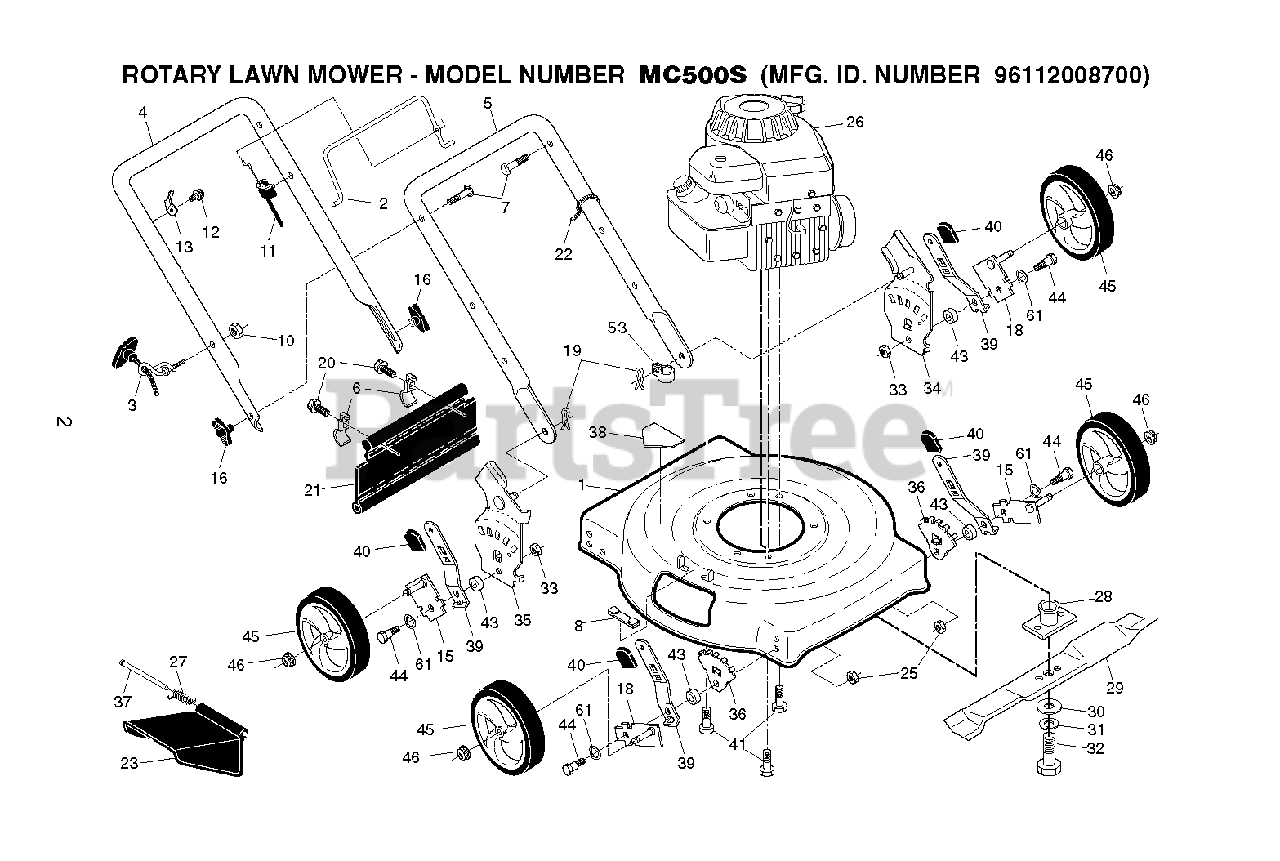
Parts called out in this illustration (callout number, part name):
1	HOUSING.22.ECON.PUSH.BLACK.WAL
2	BAIL.CONT.D.STRAIGHT.PUSH.BLK
3	GUIDE.ROPE.STD.BLK.ZIN
4	HANDLE.UPPER.ECONOMY.BLACK
5	HANDLE.LOWER.D-STRAIT.BLACK
6	BRACKET.SKIRT.BZP
7	BOLT, HANDLE 5/16-18X1.75
8	CLIP. CLOSEOUT
10	NUT
11	CABLE.MZR.RATO.22"LOW.
13	BRACKET.UPSTOP.RT
15	AXLE ARM ASSY FRONT LH
16	KNOB.WING.PLASTIC.BLACK
18	AXLE ARM ASSY FRONT RH
19	HAIRPIN COTTER
20	TAPPING SCREW
21	SKIRT.REAR.22RD/SD.FO/VE
22	TIE GUIDE
23	GUARD.DISCHARGE.22".
25	NUT.FLANGE.HEX.5/16X18.BLACK
27	SPRING.HINGE
28	ADAPTER.BLADE.W/KEY.25MM.CE
29	BLADE.22.MULCH.STANDARD
30	WASHER,HARDEN
32	BOLT.3/8-24X1.25 GR8
33	NUT.CENTERLOCK.5/16-
34	BRKT.ASM.COM.HND/ADJ.LT.BLACK
35	BRACKET.ASM.COM.HND/ADJ.RT.BLA
36	WHEEL ADJ BRACKET FRONT
37	HINGE ROD
38	No Step Decal
39	SELECTOR SPRING, FRONT
41	BOLT 3/8-16X1-1/8
43	SPACER.HEIGHT.ADJUSTER
44	SHOULDER BOLT 5/16-18
45	WHEEL.7X1.5.DMD.GS.3SPK.PGRN.1
46	NUT.HEX.FLANGE.3/8-16.LOCKNUT
53	CLIP.CABLE.BLK
61	WASHER.CURVED.CYLINDRICAL
